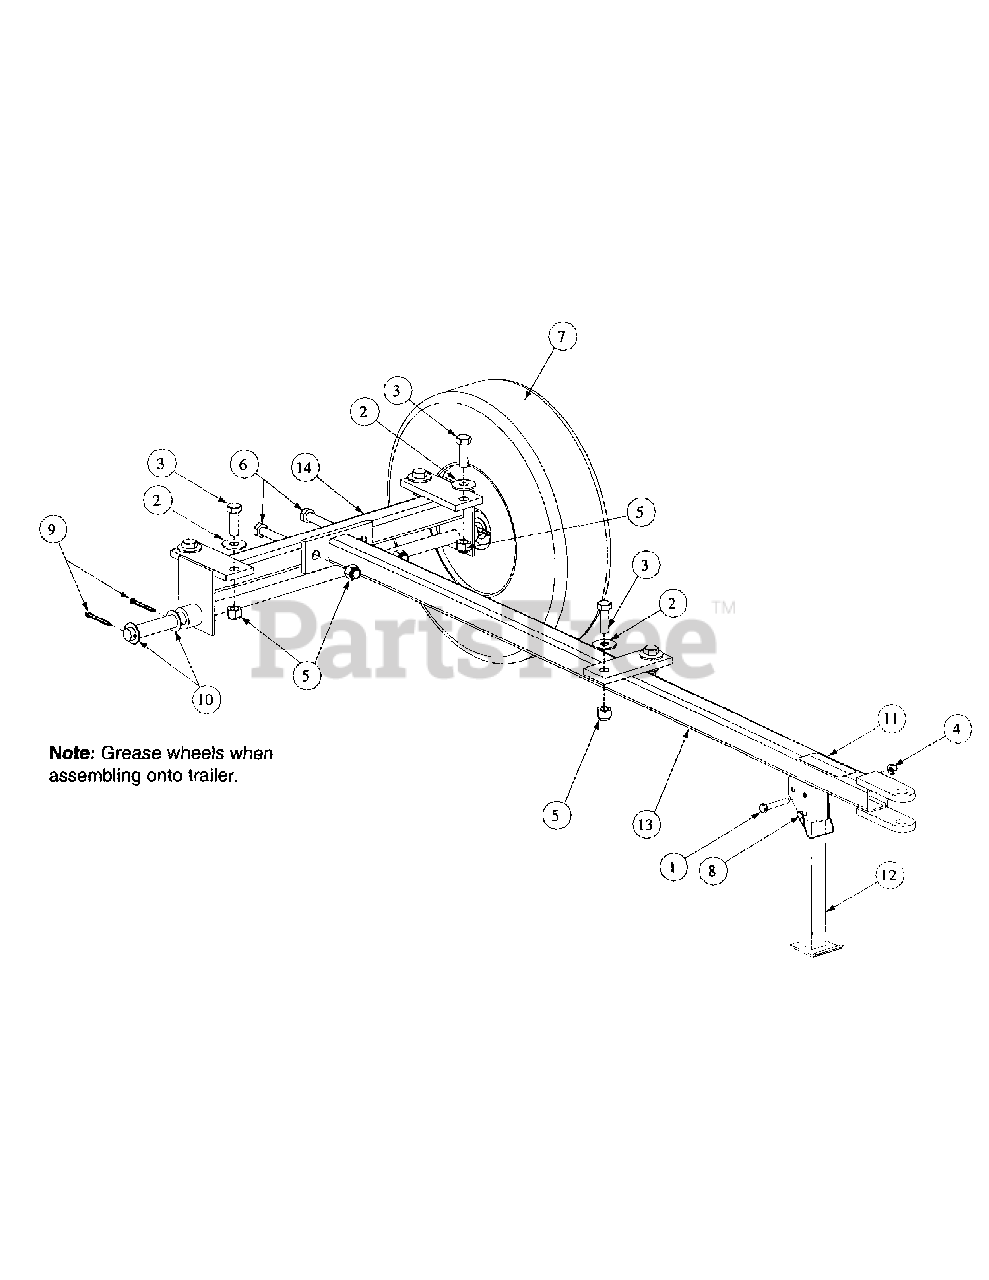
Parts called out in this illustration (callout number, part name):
1	Hex, Cap, Screw, 5/16-18, 1-3/4
2	Flat, Washer, 1/2, USS, Zinc
3	Hex, Cap, Screw, 1/2-13, 1-1/2
4	Nut, Nylock, 5/16-18
5	Lock Nut, Nylon Insert, 1/2-13
6	Hex, Cap, Screw, 1/2-13, 2-1/2
7	Tire and Wheel Assy, 4.80/4.00-8
8	Lynch Pin, 1/4, 2, Zinc
9	Cotter Pin, SS, 3/16, 1-3/4
10	Flat, Washer, SS, .06, .776, 1.25
11	Decal, "Not For Highway Use"
12	50 Gallon, Trailer Stand, Frame
13	50 Gallon, Hitch Assy, Frame
14	50 Gallon, Axle Assy, Frame
